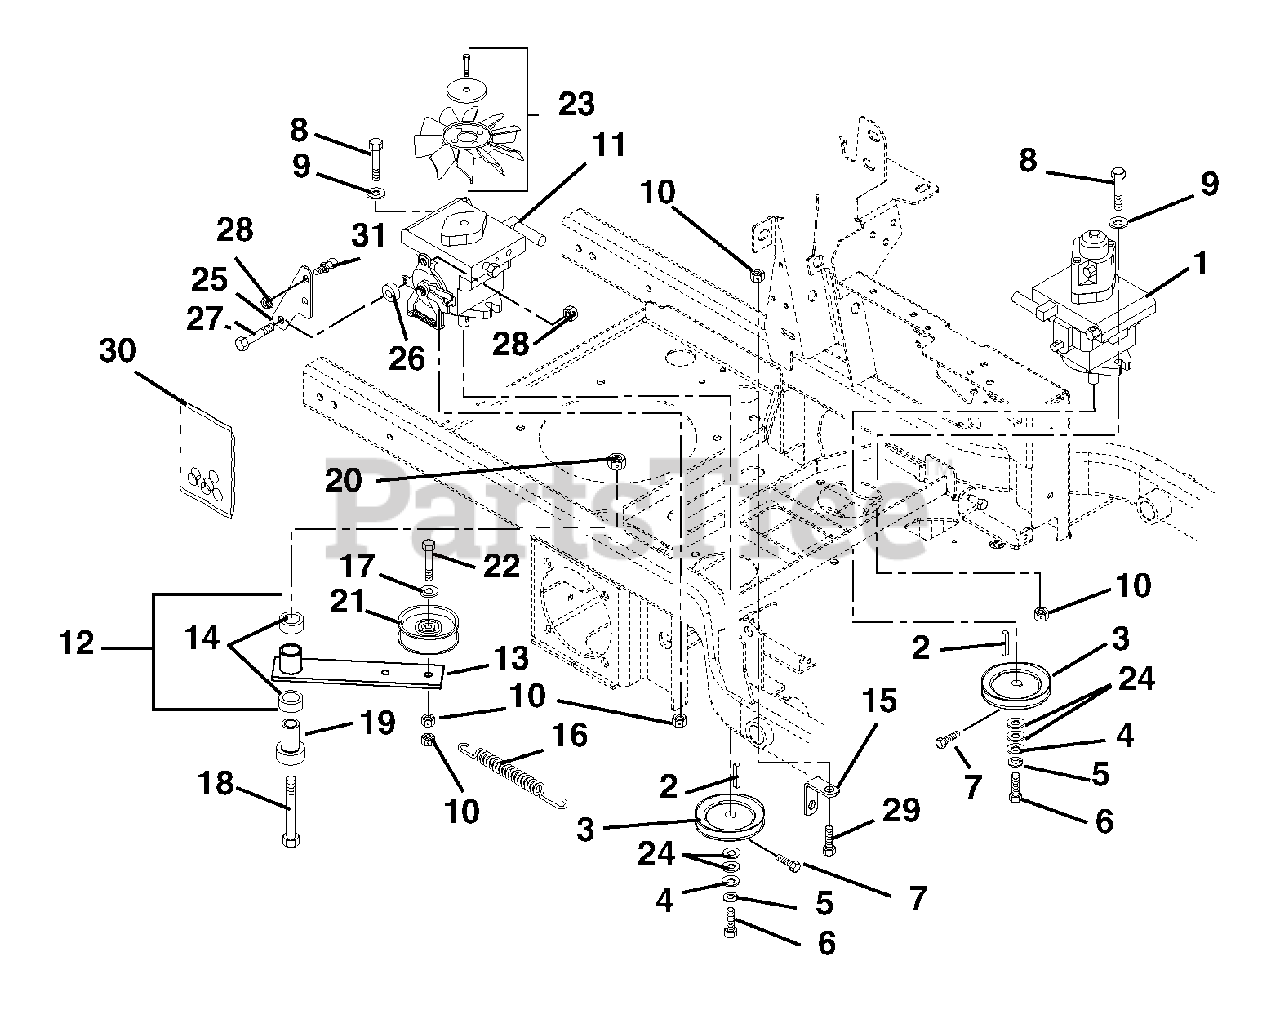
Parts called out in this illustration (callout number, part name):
1	Hydrostat BDP with Auxiliary
2	Key, Straight 5mm x 25mm x 5mm
3	Sheave 4.0 x .199
4	Washer, Flat Steel .281 x 1.00 x .063
5	Washer, Locking .25 x .062
6	Bolt, Hex M6 x 1.0 x 12
7	Bolt, Hex .25-20 x .50 Grade 5
8	Bolt, Hex .38-16 x 1.25 Grade 5
9	Washer, Flat Steel .39 x .75 x .125
10	Nut, Locking Top Flange .38-16
12	Assembly,Idler Arm Guard Drive
13	Weldment, Idler Arm Ground Drive
14	Bearing, 1.00 x 1.12 x .75
15	Anchor, Idler Spring
16	Spring, Tension .120 x .845 x 6.50
17	Washer, Flat Steel .39 x.75 x.125
18	Bolt, Hex .50-13 x 3.50 Grade 5
19	Bearing, Pedestal Powdered Metal
20	Nut, Locking Top Flange .50-13
21	Idler, Flat 4.00 x 1.06
22	Bolt, Hex .38-16 x 2.25 Grade 5
23	Fan, Cooling
24	Washer, Flat Steel .656 x 1.31 x .095
25	Bracket, Return to Neutral/Damper
26	Spacer .344 x 1.00 x .375
27	Bolt, Hex .31-18 x 1.25 Grade 5
28	Nut, Locking Top Flange .31-18
29	Bolt, Hex .38-16 x .75 Grade 5
30	Kit, Pump Seal (BDP-10A)
31	Stud, Ball
